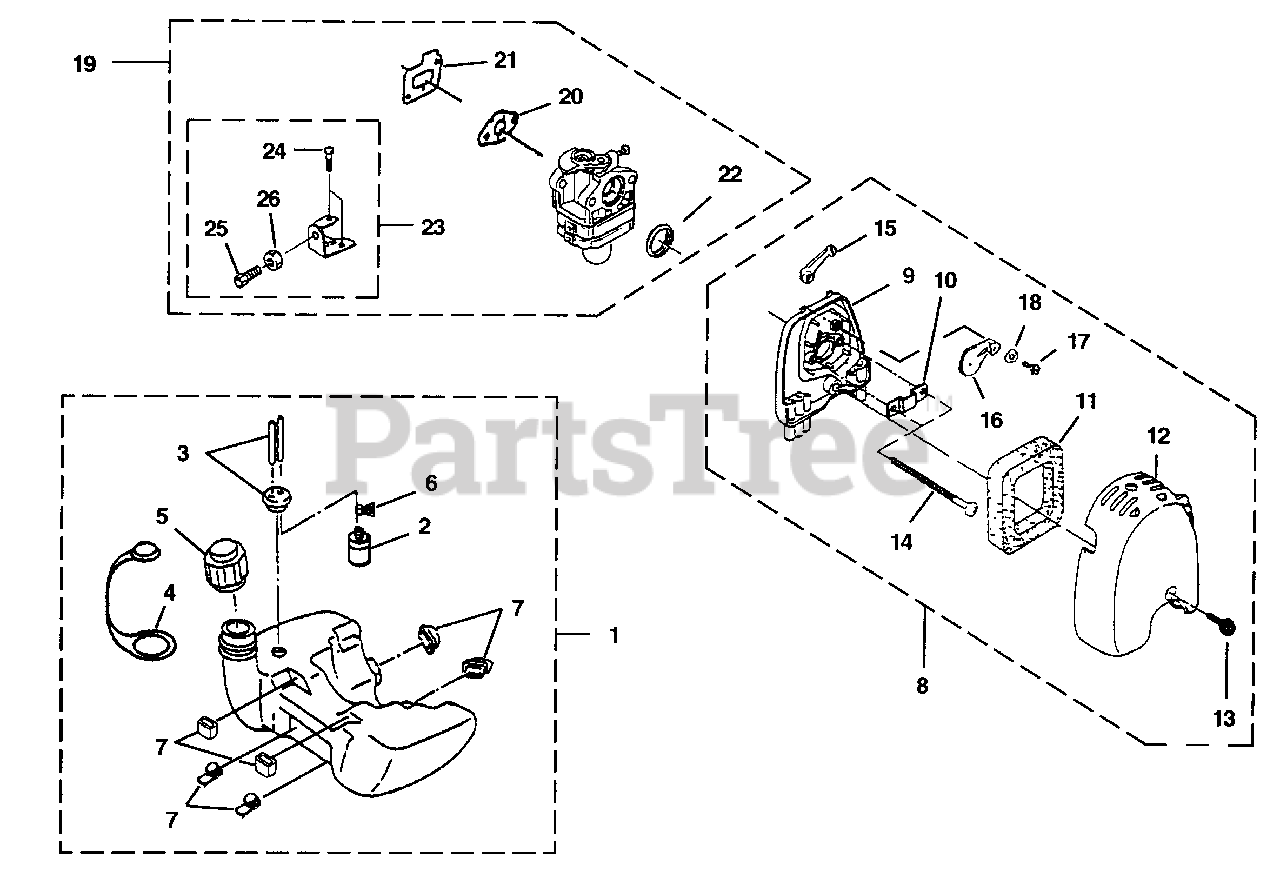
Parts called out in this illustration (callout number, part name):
1	FUEL TANK ASSEMBLY
2	FILTER-Fuel
4	CAP-Retainer
5	CAP-Fuel
6	CLAMP-Hose
7	RUBBER BUMPER KIT
8	AIR FILTER ASSEMBLY
9	PLATE-Air Filter Assembly
10	PLATE-Air Filter
11	FILTER-Air
12	COVER-Air Filter
13	SCREW ASSEMBLY (M5 x 14)
14	SCREW (M5 x 50)
15	LEVER Choke
16	PLATE-Choke
17	SCREW-Tapping
18	WASHER
19	CARBURETOR ASSEMBLY
20	GASKET-Carburetor
21	GASKET-Heat Dam
22	RING-Packing
23	CABLE BRACKET ASSEMBLY
24	SCREW-Throttle Collar (M5 x 18)
25	SCREW-Cable Adjust
26	NUT-Cable Adjust
